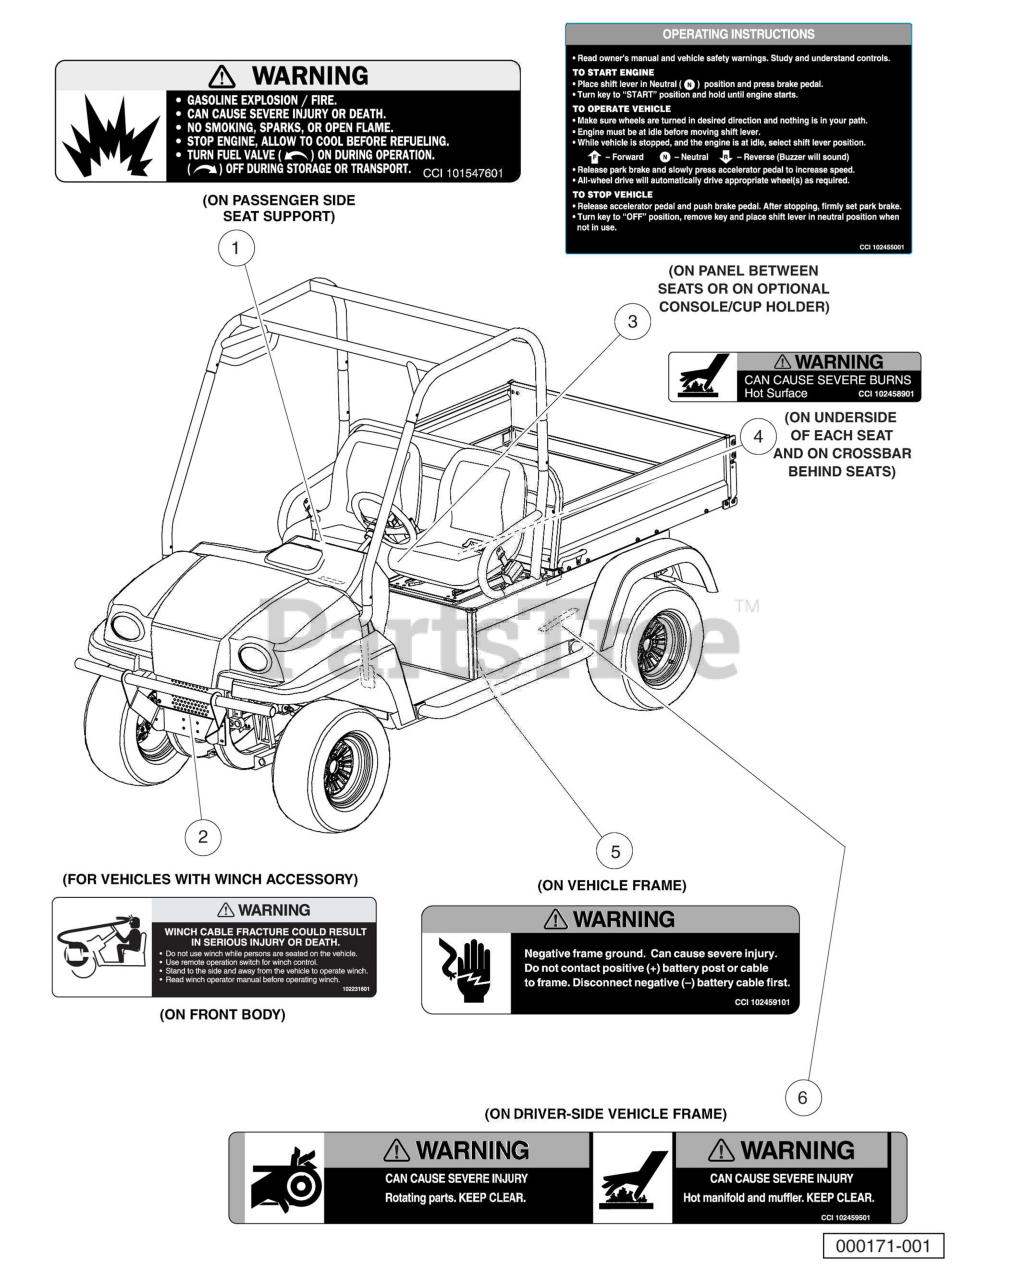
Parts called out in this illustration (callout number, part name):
1	Decal, Gasoline Explosion/Fire Warning
2	Decal, Winch Cable Fracture Warning
3	Decal, Operating Instructions, Gasoline
4	Decal, Hot Surface Warning
5	Decal, Frame Ground Warning
6	Decal, Rotating Parts and Hot Exhaust Warning
